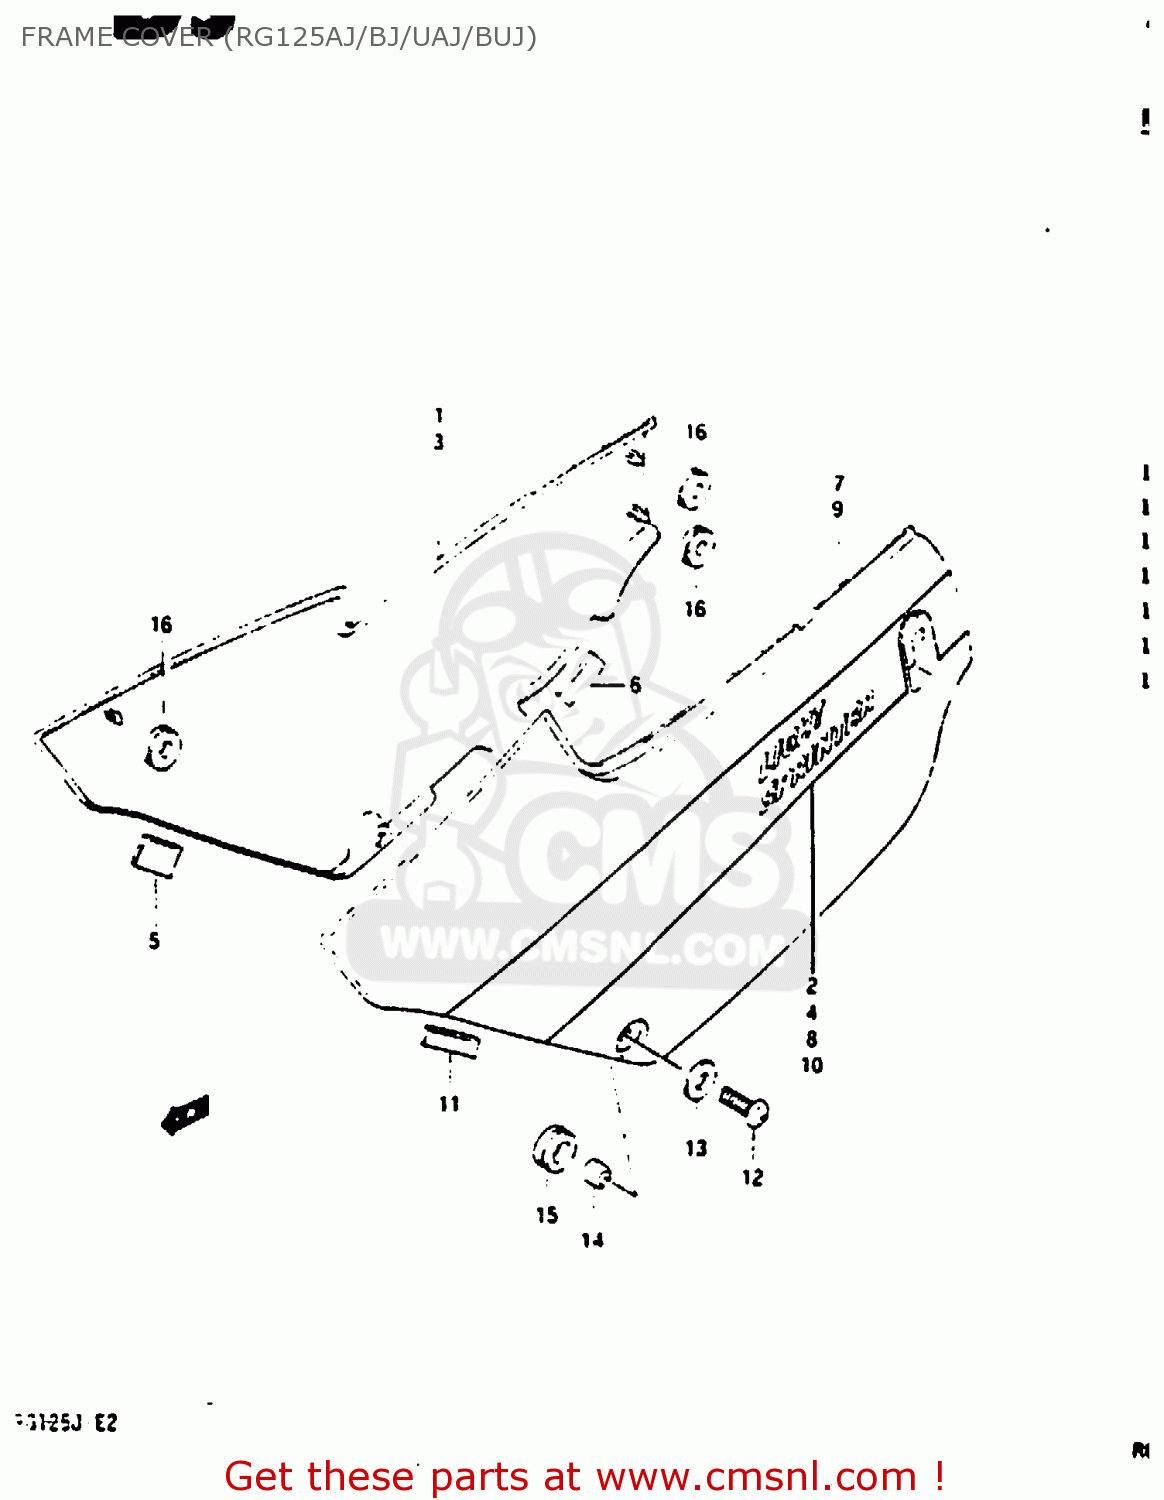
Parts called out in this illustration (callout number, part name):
1	COVER, FRAME RH (WHITE)
2	TAPE, FRAME COVER RH
3	COVER, FRAME RH (BLACK)
4	TAPE, FRAME COVER RH
5	CUSHION, FRONT RH
6	CUSHION, REAR RH
7	COVER, FRAME LH (WHITE)
8	TAPE, FRAME LH (BLACK)
9	COVER, FRAME LH (BLACK)
10	TAPE, FRAME COVER LH
11	CUSHION, LH
12	SCREW
13	WASHER(6.5X18X1)
14	SPACER (6.1X9X9)
15	CUSHION
16	CUSHION
